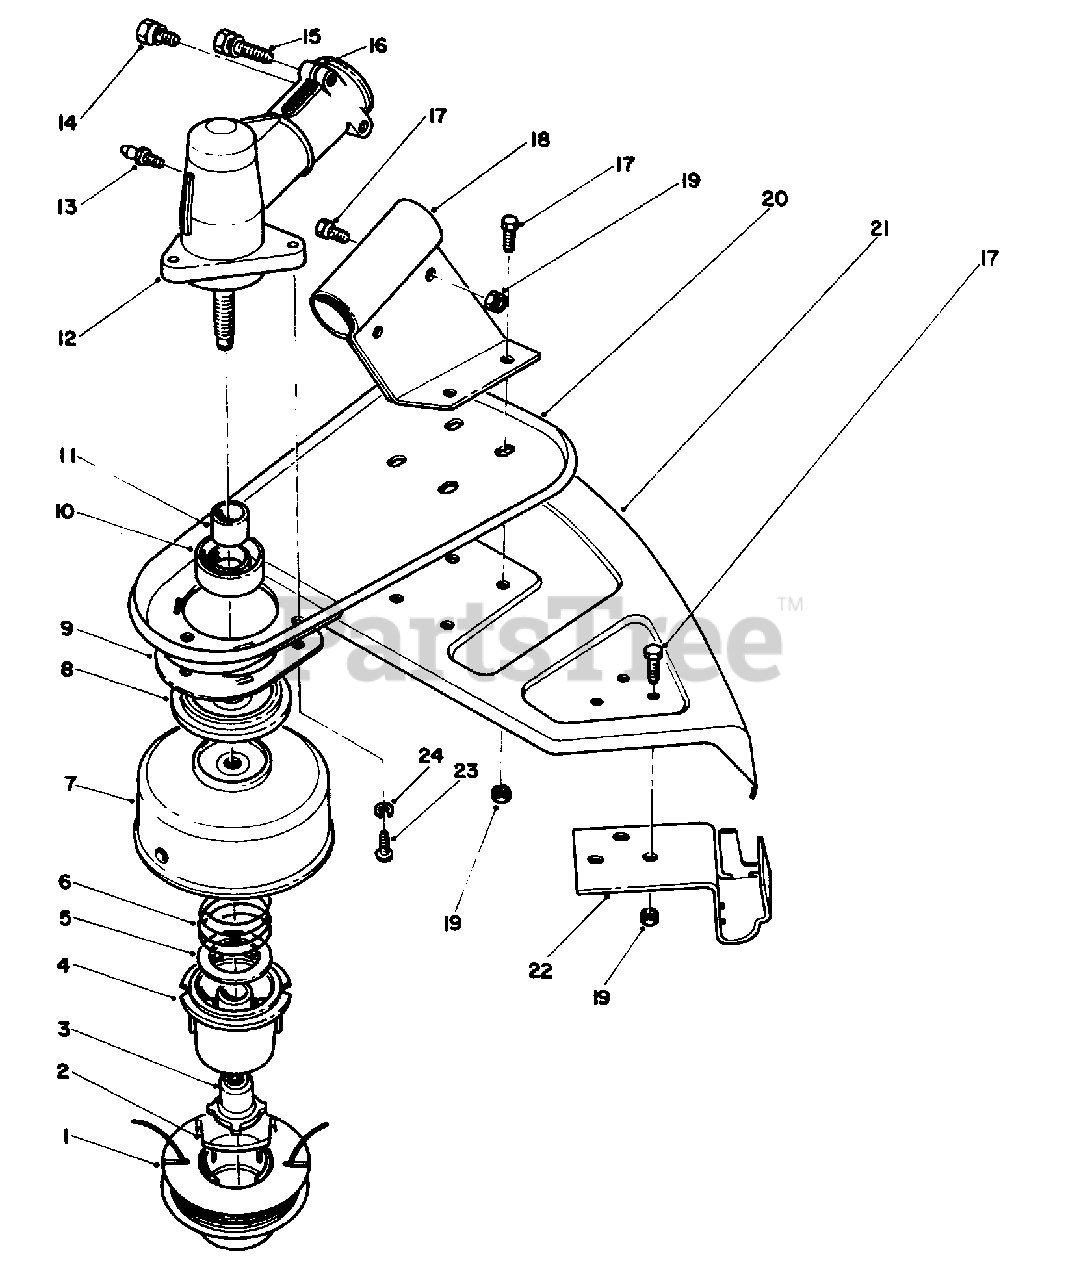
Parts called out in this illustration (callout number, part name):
1	Prewound Spool
2	Saddle-Spool Cap
3	Driver L. H.
4	Core-Spool
6	Spring-Compression
7	Drum Assembly w/Eyelets
8	Cap-Dust
9	Guard-Grass Wrap
10	Seal-Oil
11	Sleeve-Spline
12	Gear Box Assembly (Incl. Ref. #10, 11, & 13-16)
13	Fitting-Grease
14	Hex Hd. Machine Screw
15	Hex Hd. Machine Screw
17	Hex Hd. Machine Screw
18	Bracket-Shield
19	Locknut
20	Support-Shield
21	Shield-Grass
22	Bracket & Knife Blade Ass'y
23	Screw-Guard
24	Lockwasher
